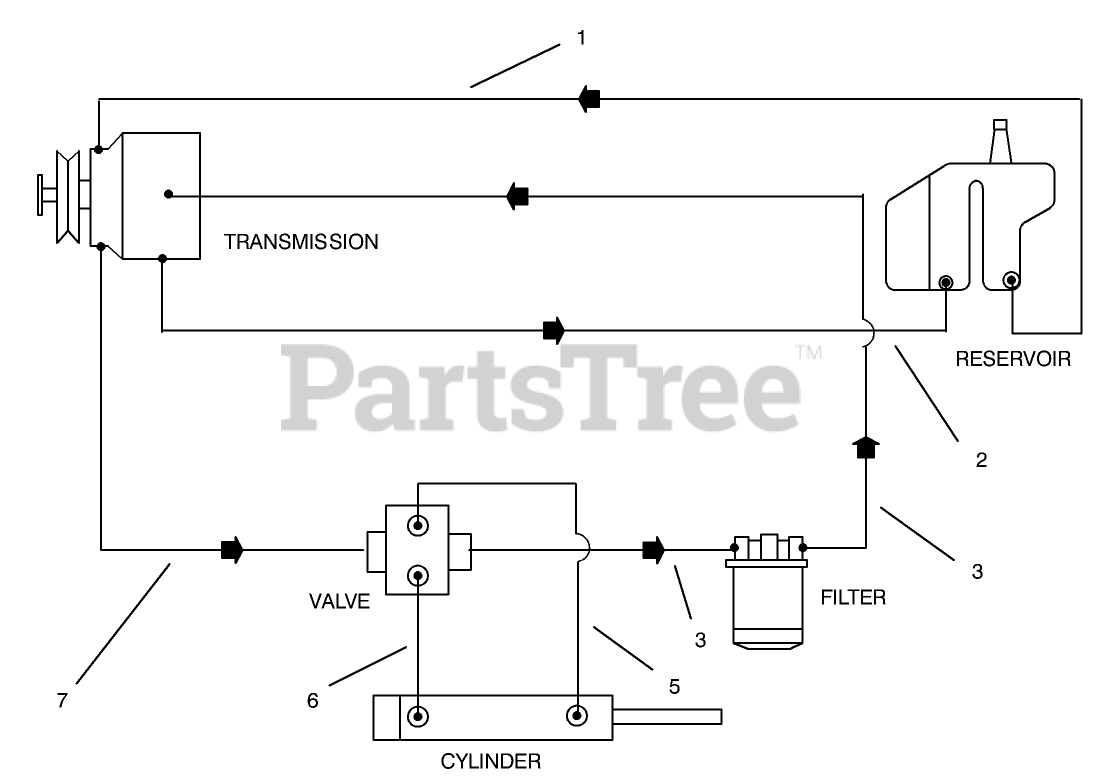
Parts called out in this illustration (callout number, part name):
1	HOSE-RESV TO PUMP
3	HOSE-ASM - HYD
5	HOSE ASM
6	HOSE ASM
7	HOSE ASM
